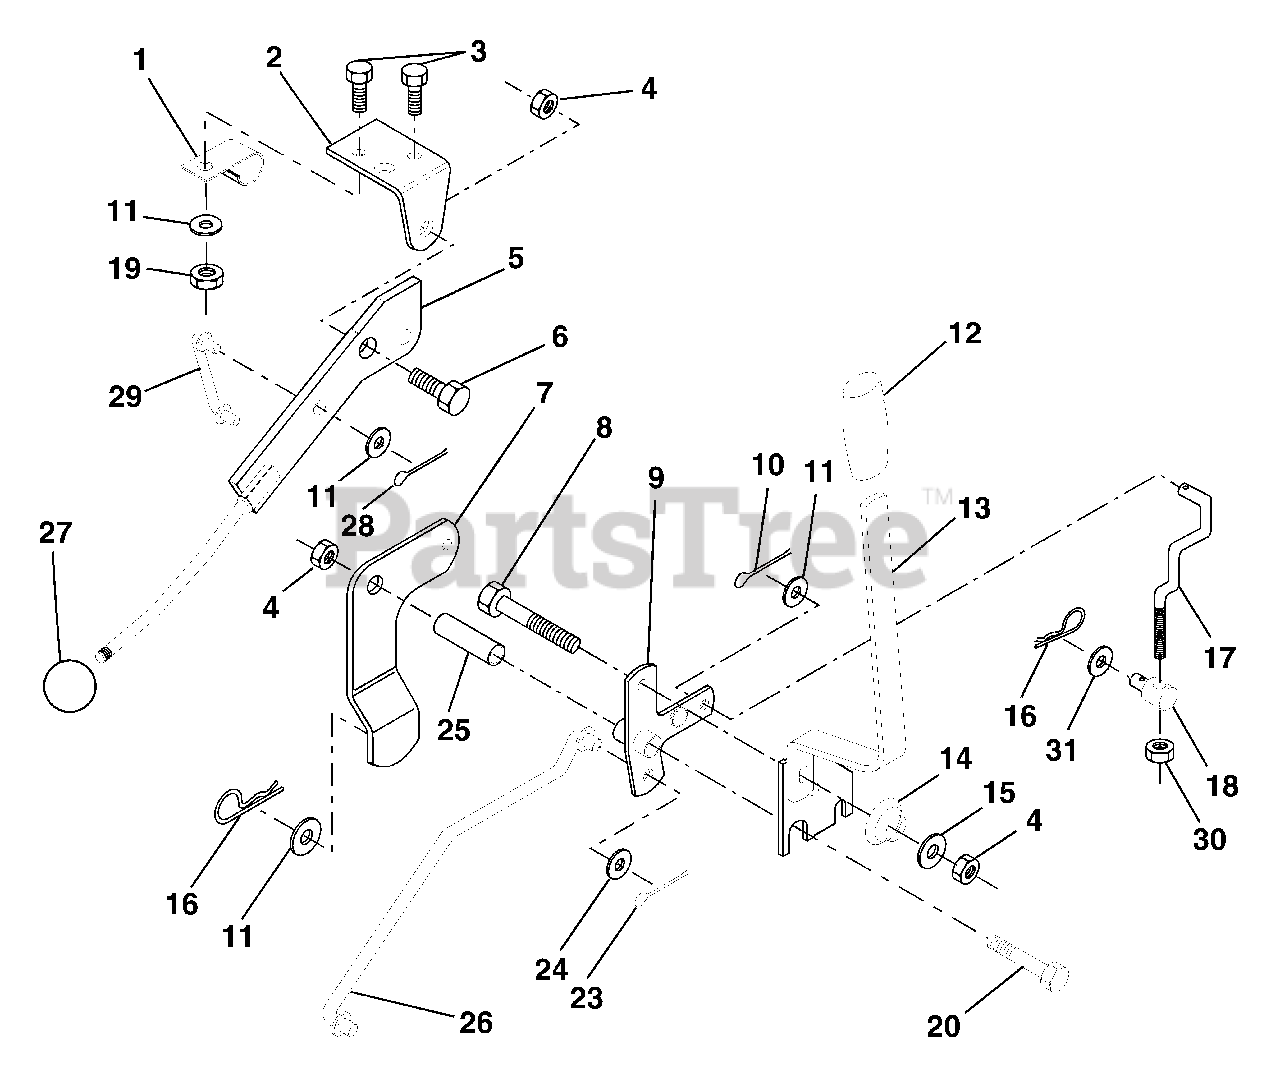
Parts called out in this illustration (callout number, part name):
1	Clip, Insulated
2	Bracket, Mower Clutch
3	Bolt, Fin. Hex 1/4-20 UNC x 1/2
4	Nut, Crownlock 3/8-16
5	Assembly, Clutch Lever
6	Bolt, Shoulder
7	Assembly, Mower Clutch Arm
8	Bolt, Hex 3/8-16 UNC x 2-1/4
9	Assembly, Bellcrank Lift
10	Pin, Cotter 1/8 x 3/4
11	Washer 13/32 x 13/16 x 16 Ga.
12	Grip, Handle
13	Assembly, Lift Handle
14	Spring, Compression
15	Washer 13/32 x 3/4 x 12 Ga.
16	Retainer, Spring
17	Link, Front Lift
18	Trunnion, Threaded 3/8-16
19	Nut, Crownlock 1/4-20
20	Bolt, Fin. Hex 3/8-16 UNC x 2-3/4
23	Pin, Cotter 1/8 x 1
24	Washer 17/32 x 1-1/4 x 12 Ga.
25	Tube, Spacer
26	Rod, Mower Lift
28	Pin, Cotter 3/32 x 3/4
29	Link, Mower Clutch
30	Nut Hex Jam 3/8-16 x 1.30
31	Washer 13/32 x 1 - 1/4 x 12 Ga.
